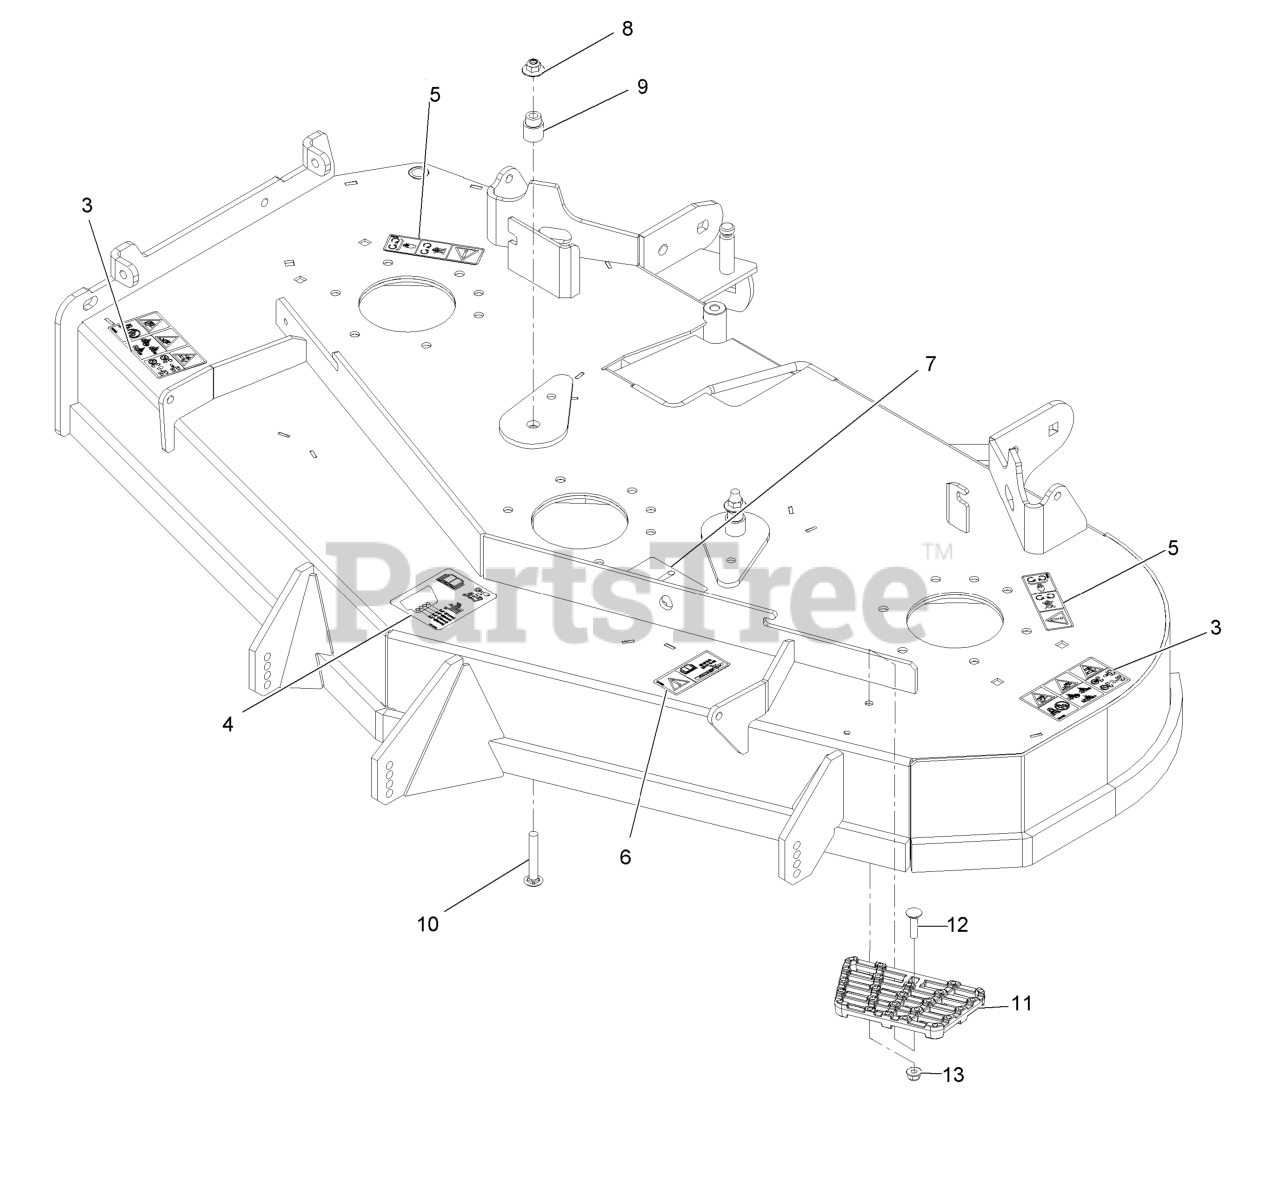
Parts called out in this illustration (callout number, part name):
3	Decal-Danger Thrown Objects
4	Decal-Roller, Anti-Scalp
5	Decal-Cover, Missing
6	Decal-Bolt Torque
7	Decal-Belt Routing
8	Nut-Nyloc 3/8-16 Flg
9	Bushing, Idler
10	Bolt-Carriage 3/8-16 X 2 1/2
11	Step-Deck
12	Bolt-Carriage 5/16-18 X 1 1/4
13	Nut-Nyloc 5/16-18 Flg
